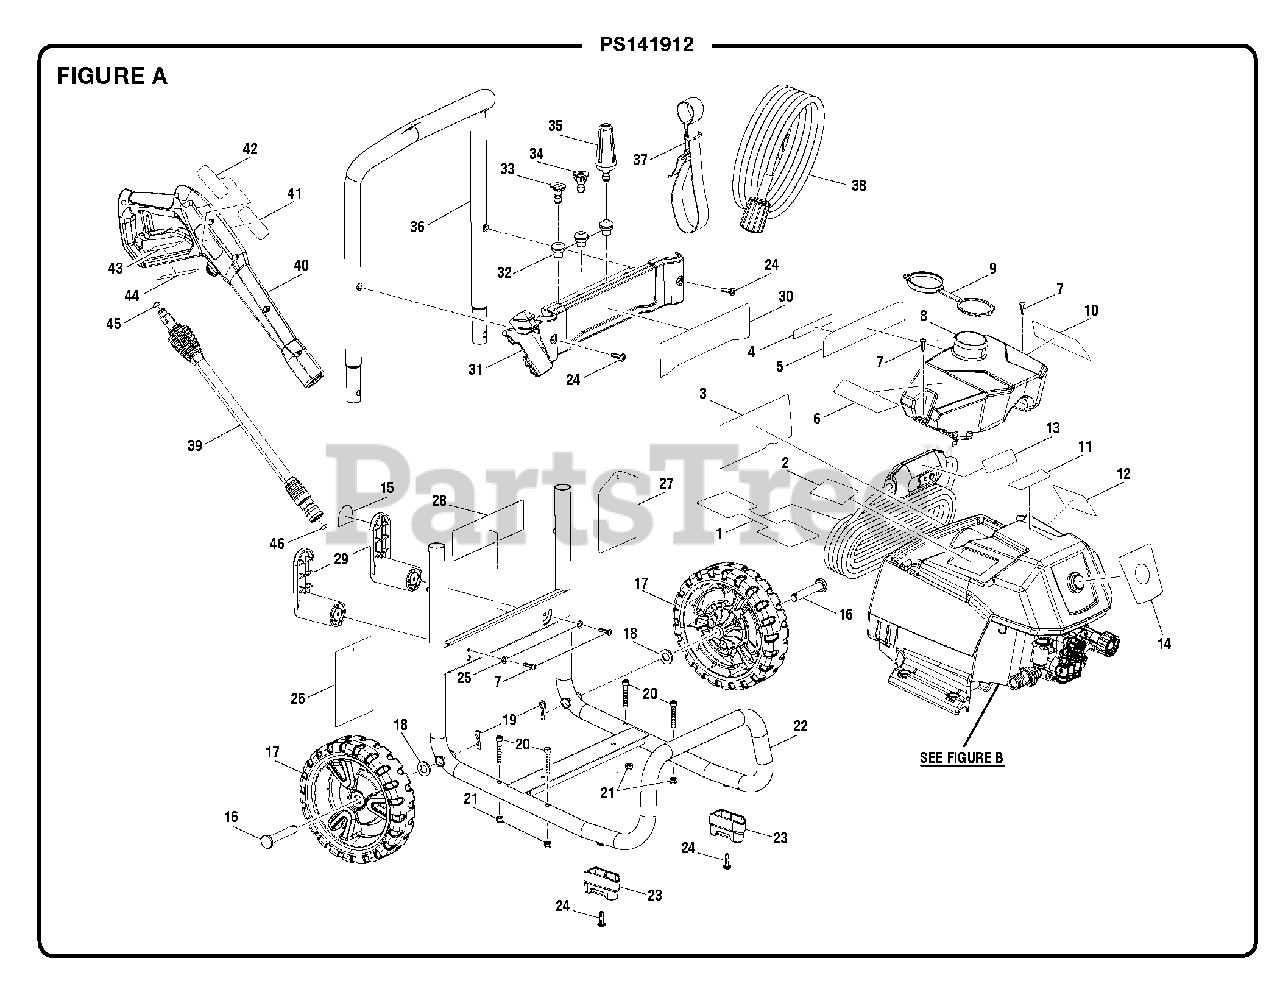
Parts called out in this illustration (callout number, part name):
1	Cord Wrap Label
2	Vent Label (Left)
3	Danger Label
4	Inquires Label
5	Quick Start Label
6	Nozzle Select Label
7	Screw (M4.8 x 19 mm, Pan Hd.)
8	Detergent Tank
9	Detergent Tank Cap
10	Detergent Tank Label
11	Logo Label
12	Vent Label (Right)
13	Cord Plug Label
14	On/Off Switch Label
15	Cord Unlock Label
16	Axle
18	Washer (ID12.5 x OD24 x 2t)
19	Hitch Pin
20	Bolt (M6 x 40 mm Hex. Soc. Hd.)
21	Lock Nut (M6)
24	Bolt (M6 x 20 mm, Pan Hd.)
25	Washer (M6)
26	Warning/Notice Hangtag
27	Nozzle Hangtag
28	Regulatory Label
29	Cord Wrap Arm
30	Performance Label
31	Front Panel
32	Nozzle Grommet
33	Soap Nozzle
34	Nozzle (15 deg)
35	Turbo Nozzle
36	Handle Assembly
37	Hose Storage Strap
38	Hose (25 ft.)
39	Spray Wand
40	Trigger Handle
41	Trigger Handle Warning Label (English)
42	Logo Label
43	Trigger Handle Warning Label (French/Spanish)
44	Trigger Handle Rating Label
45	O-Ring (8 x 2 mm)
46	O-Ring (9.5 x 2.6 mm)
